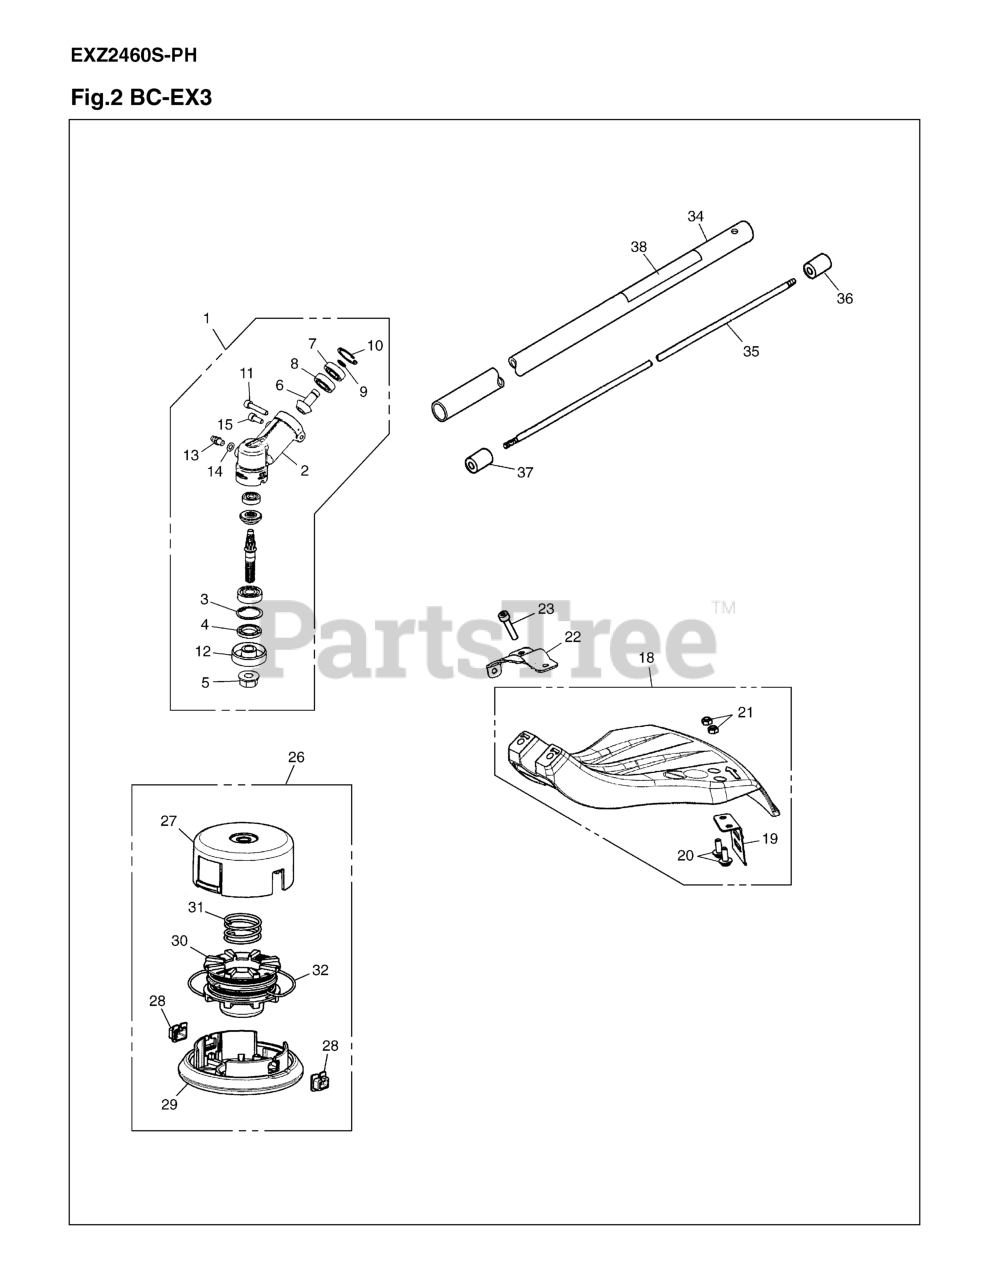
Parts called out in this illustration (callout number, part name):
1	GEARCASE ASSY
2	GEARCASE
3	RING,SNAP M26x1.
4	SEAL, OIL(RPLS 3
8	BEARING
9	SNAP RING
10	RING, SNAP, M24
11	BOLT, TORX
12	HOLDER (A)
13	FITTING, GREASE
14	WASHER, M6 x .8
15	BOLT, TORX
18	GUARD ASSY
20	SCREW
23	BOLT, TORX
26	4
28	EYELET
29	COVER (RPLS T318
30	HOLDER, CORD (RP
32	CORD
34	PIPE COMPLETE
36	JOINT, SHAFT (RP
37	SPACER
38	PLATE NAME
